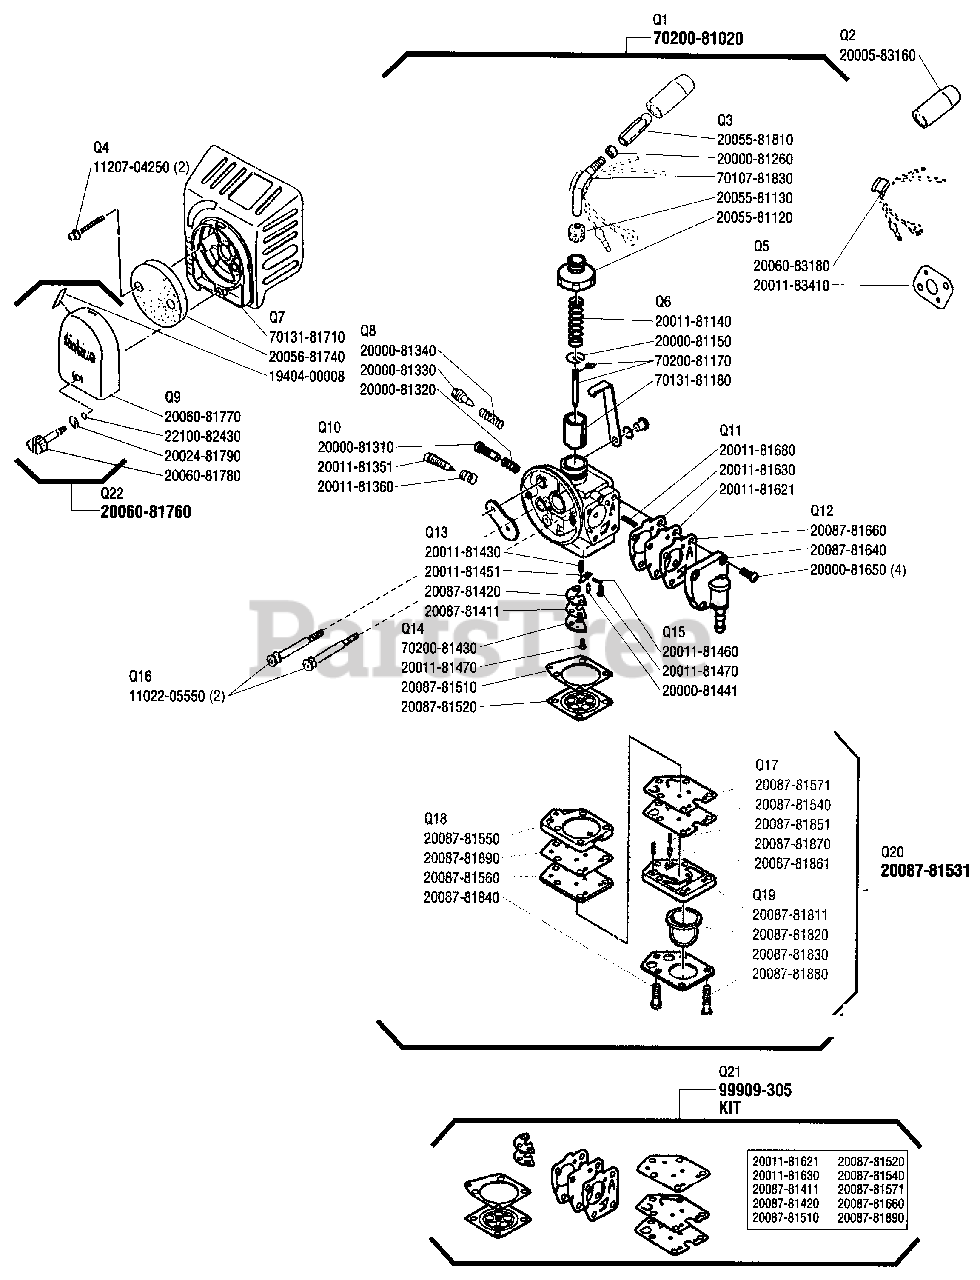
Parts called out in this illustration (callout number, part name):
Q1	CARBURETOR
Q2	CAP, CARBURETOR
Q3	PIPE, CABLE ADJUSTER
Q3	NUT, LOCK
Q3	CAP, CARBURETOR
Q3	CAP, DUST
Q3	ADJUSTER, CABLE
Q4	SCREW
Q5	TUBE, PROTECTIVE
Q5	GASKET
Q6	WASHER, SPRING SUPPORT
Q6	SPRING
Q6	VALVE, SLIDE
Q6	NEEDLE, JET
Q7	LABEL, CHOKE
Q7	FILTER, AIR
Q7	AIR FILTER CASE ASSY
Q8	SPRING
Q8	SCREW, SLOW AIR
Q9	KNOB
Q9	WASHER, CONE M6
Q9	COVER, AIR FILTER
Q9	O-RING
Q10	SCREW, IDLE ADJUST
Q10	SCREW, MAIN ADJUST
Q10	SPRING
Q11	SPRING, COIL
Q11	DIAPHRAGM, METERING
Q11	GASKET, DIAPHRAGM
Q12	SCREW
Q12	PUMP BODY
Q12	VALVE, PUMP
Q13	SPRING
Q13	LEVER, METERING
Q13	VALVE, CHECK
Q13	GASKET
Q14	SCREW M3×8
Q14	GASKET, METERING DIAPHRAGM
Q14	DIAPHRAGM, METERING
Q14	PLATE
Q15	SCREW M3×8
Q15	VALVE, INLET NEEDLE
Q15	PIN, METERING LEVER
Q16	BOLT
Q17	GASKET
Q17	VALVE, CHECK
Q17	SPRING
Q18	COVER, PUMP
Q18	PLATE, PUMP
Q18	SCREW
Q18	GASKET
Q19	COVER, PUMP
Q19	BULB, PURGE
Q19	RETAINER, PURGE BULB
Q19	SCREW 3×20
Q20	PURGE PUMP KIT
Q21	DIAPHRAGM/GASKET KIT
Q22	COVER ASSY, AIR FILTER
